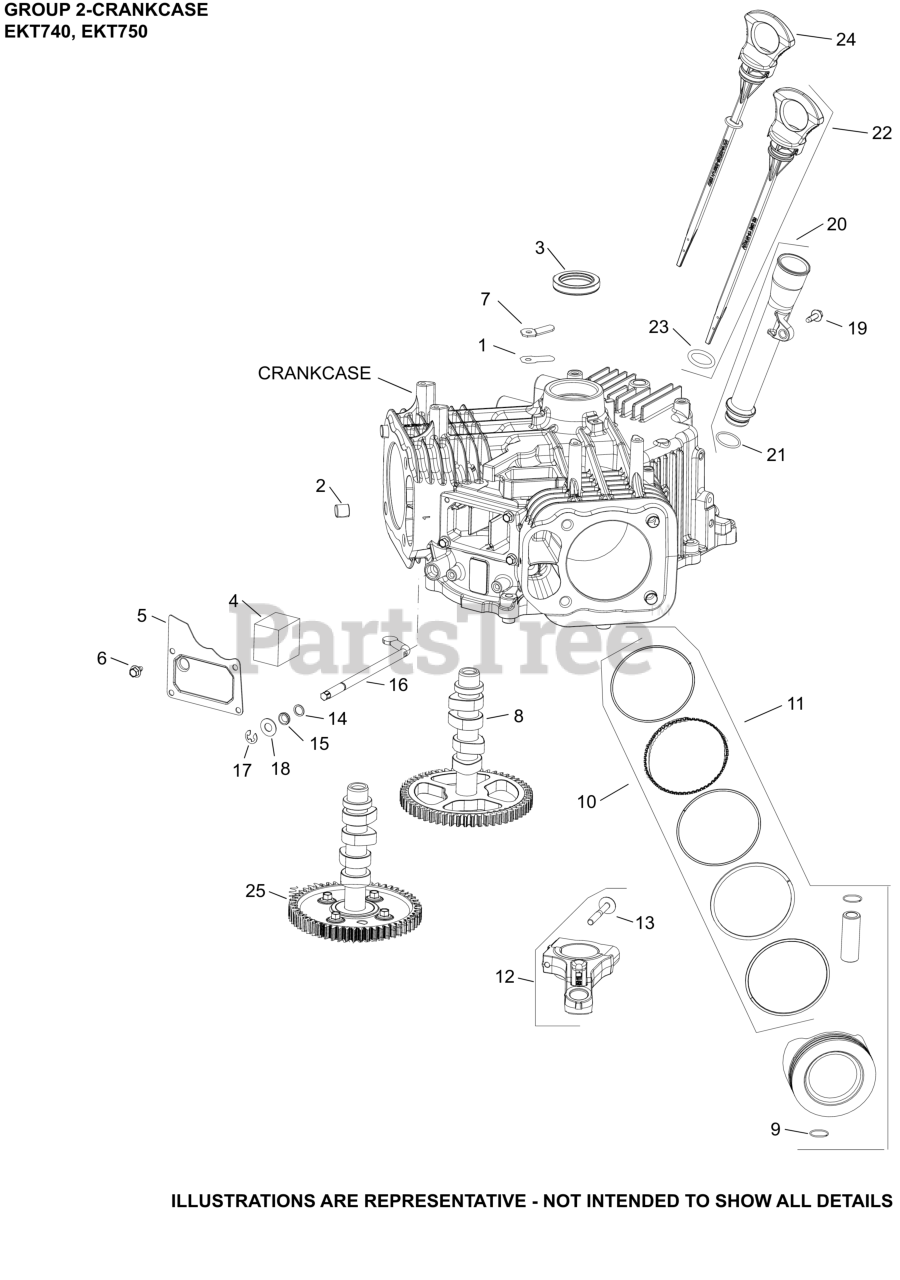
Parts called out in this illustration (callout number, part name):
1	REED, BREATHER
2	PIN, LOCATING
3	SEAL, OIL (HELIX LIP)
4	FILTER, BREATHER
5	COVER, BREATHER MEDIA
7	RETAINER, REED
8	CAMSHAFT ASSY
9	RETAINER, PISTON PIN
11	KIT,PSTN/RNG STYLE B(STD)
12	ROD, ASSEMBLY CONNECTING
14	WASHER, FLAT 11/32"
15	SEAL, GOVERNOR CROSS SHAFT
16	KIT, CROSS SHAFT
17	CLIP, RETAINER GOVERNOR SHAFT
18	WASHER, FLAT 9 MM
19	SCREW, THREAD FORMING
20	TUBE ASSEMBLY, OIL FILL
22	DIPSTICK, ASSY
